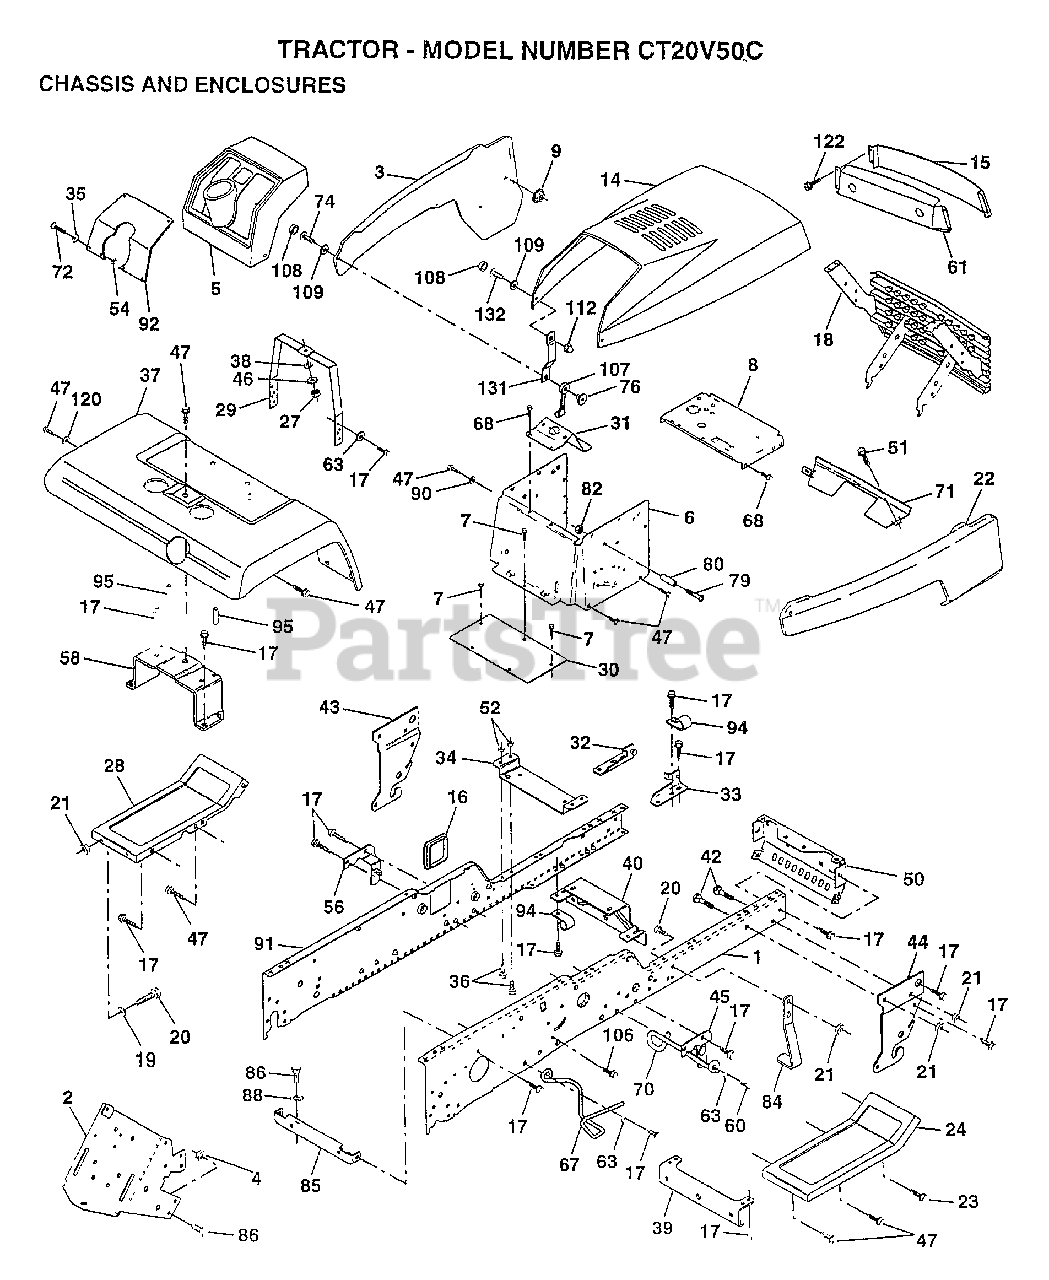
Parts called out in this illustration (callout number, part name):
1	"RAIL,FRAME RH"
2	DRAWBAR GT
3	PANEL PNT LH SIDE
4	NUT GTV
5	DASHBOARD BLACK
6	DASH LOWER
7	SCREW
8	SUPPORT.DASH.BTRY
9	PAL NUT LT
14	HOOD PNT YARDPRO
15	LENS.BAR.CLEAR
16	COVER ACCESS
17	SCREW
19	WASHER
20	BOLT
22	PANEL PNT RH SIDE
23	SCREW GTV
24	FOOTREST.RH.LT/GT
28	FOOTREST.LH.LT/GT
29	DASH.SUPT.YP/HUSQ
30	SADDLE.SCR.6SP
31	BRAKET.SUPT.STEER
32	BRACKET ASM FRAME
33	BRACKET ASM FRAME
34	BRACKET.ENG.SUPT.
35	WASHER
36	BOLT
37	FENDER.PNT.MS-550
38	LOCKWASHER
39	BRACKET.AXLE.FRT.
40	"BRKT SUPPORT,AXLE"
43	BRACKET.SUS.FT.LH
44	BRACKET.SUS.FT.RH
45	BRACKET.SUSP.RH.
46	WASHER PM
47	SCREW LT
50	"BRKT CHASSIS,FRNT"
51	SCREW CRT
56	BRACKET.SUSP.LH.
58	BRKT.ASM.FENDER
60	SCREW
63	WASHER
67	"GUIDE BELT, T/A"
68	SCREW LT
70	GUIDE.BELT.MID.SP
71	STRAP.PNT.GRILLE
72	SCREW
74	SCREW
76	WELDNUT
79	SCREW
80	SPACER LT
84	STOP.OVER.CENTER
85	BRACKET.SUPT.TRAN
86	BOLT
88	LOCKWASHER
90	LOCKWASHER
91	"RAIL FRAME,LH"
92	"PLATE DASH,SLKSCR"
94	CLIP GTV
95	NUT-PUSH YT
107	HOOD LATCH T
108	SNAP CAP LT
109	WASHER LT
112	ACORN NUT RB
120	WASHER HYT
131	BKT.SPT.HOOD/PANL
132	SCREW.10-24X3/8.
